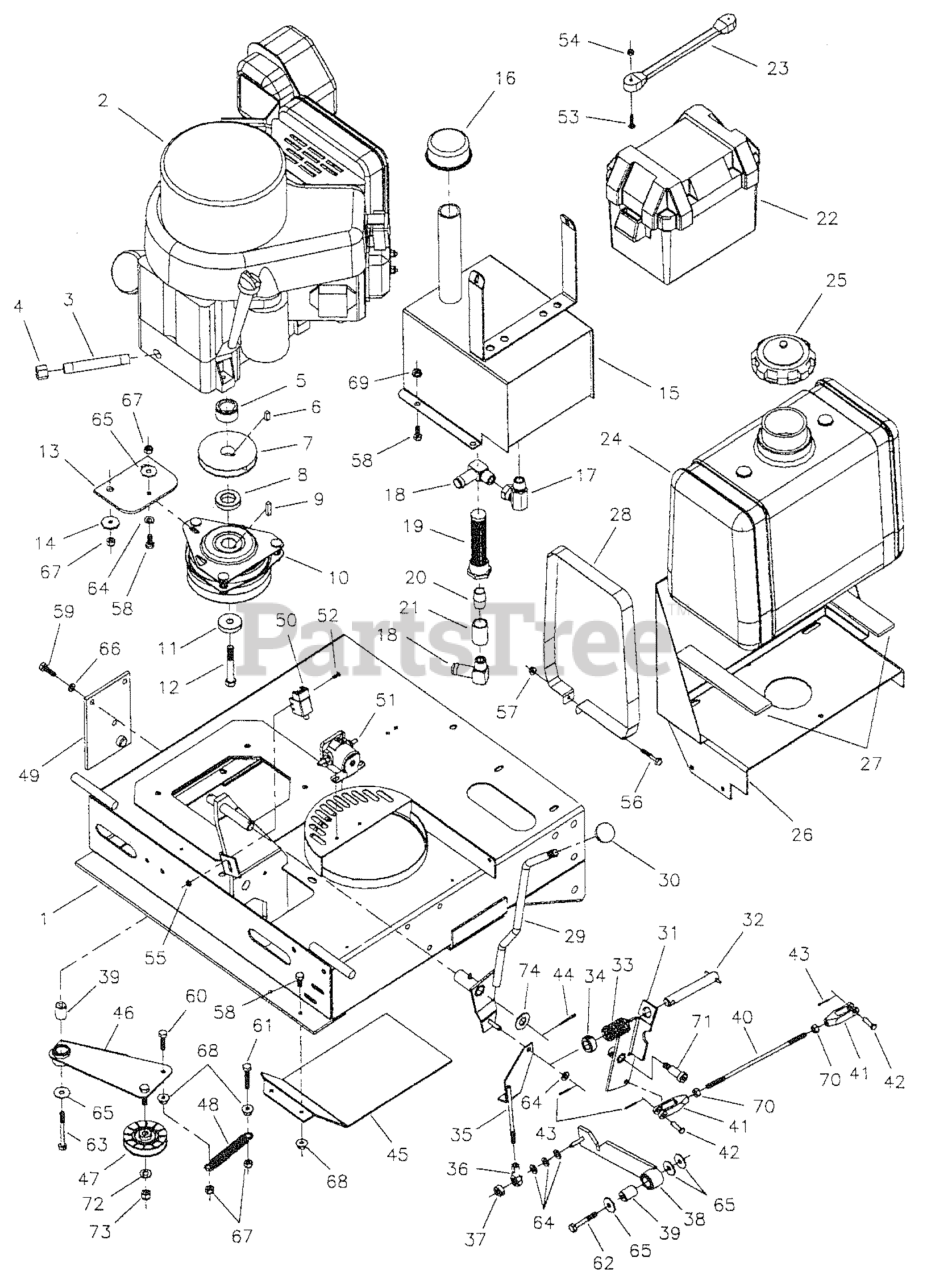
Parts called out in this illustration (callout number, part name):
1	Engine Deck
3	Nipple, 3/8 NPT x 4-1/2"
4	Cap, 3/8 NPT
5	Spacer, Crank Shaft
6	Key, 1/4" Sq. x 5/8"
7	Pulley, Crank Shaft
8	Spacer, Clutch
9	Key, 1/4" Sq. x 1"
10	Clutch, Electric
11	Washer, Clutch Retaining
12	Bolt, On-Lock
13	Pad, Clutch Mount
14	Washer, Clutch Anchor
15	HYDRO TANK WELDMENT
16	BREATHER
17	Fitting, 900 1/2 NPT Swivel
18	Fitting, 90° 1/2 NPT
19	Strainer, In-Line
20	Nipple, 1/2 NPT Close
21	Coupler, 1/2 NPT
22	Box, Battery
23	Strap, Rubber
24	TANK, FUEL, PLASTIC, 6 GALLON W/ FUEL LINE
25	CAP, FUEL TANK, 3-1/2 NECK
26	Mount, Fuel Tank
27	Pad, Rubber Mount
28	Strap, 6 GaL Fuel Tank
29	Brake Lever
30	Knob
31	Brake Rocker Arm
32	Bar, Spring
33	Spring, Compression
34	Collar, 5/8 Set
35	Brake Lock
36	BALL JOINT 5/16-24 RH FEMALE BRONZE RACE
37	Collar, 5/16 Set
38	Neutral Lock wi Bushing
38	Bushing, Brass
39	Spacer, Pivot
40	Rod, Brake Linkage
41	Clevis, 5/16 Plastic
42	Pin, Clevis
43	PIN, 3/32 X 0.750, COT, ZINC/CLEAR
44	PIN, COTTER, 1/8 X 1-1/4
45	Plate, Skid
46	Idler Arm wi Bushing
46	Bushing, Brass
47	Pulley, Idler
48	Spring, Extension
49	WELD, BRACKET, PIVOT - LEFT
49	WELD, BRACKET, PIVOT - RIGHT
50	SWITCH, PLUNGER, N.O./N.C.
51	Solenoid, Starter
52	Screw, #10-24 x 1/2 Slotted
53	SCREW, #10-24 X 1 RS, CZ
54	Nut. #10-24 Hex Nylon Lock
55	Nut, #10-24 Hex
56	Bolt, 1/4-20 x 1-1/2 GD.5
57	NUT, 1/4-20 HEX SERR. FLANGE
58	BOLT, 5/16-18 X 3/4 GD5
59	Bolt, 5/16-18 x I GD.5
60	BOLT, 5/16-18 X 1-1/4 GD5 TFL, CZ
61	Bolt, 5/16-18 x 1-3/4 TFL GD.5
62	Bolt, 5/16-18 x 2 GD.5
63	Bolt, 5/16-18 x 3 OD.S
64	WASHER, 5/16" SAE
65	Washer, 5/16 Fender
66	WASHER, 5/16 LOCK CZ
67	Nut, 5/16-18 Hex Nylon Lock
68	NUT, 5/16-18 HEX SERRATED FLANGE (LARGE)
69	NUT, 5/16-18 HEX SERRATED FLANGE (SMALL)
70	Nut, 5/16-24 Hex
71	Bolt, 3/8-16 -1/2 Dia. x 1" Shoulder
72	WASHER, 3/8 SAE
73	NUT, 3/8-16 HEX NYLON LOCK
74	Washer, 5/8 SAE
75	Fuel Line, 25" Long (tank to filter)
76	Filter, Fuel
77	Fuel Line, 19" Long (filter to engine)
78	Clamp, Hose (for fuel line)
79	Wire Loom, 24" Long (covers fuel line #1550831-25)
